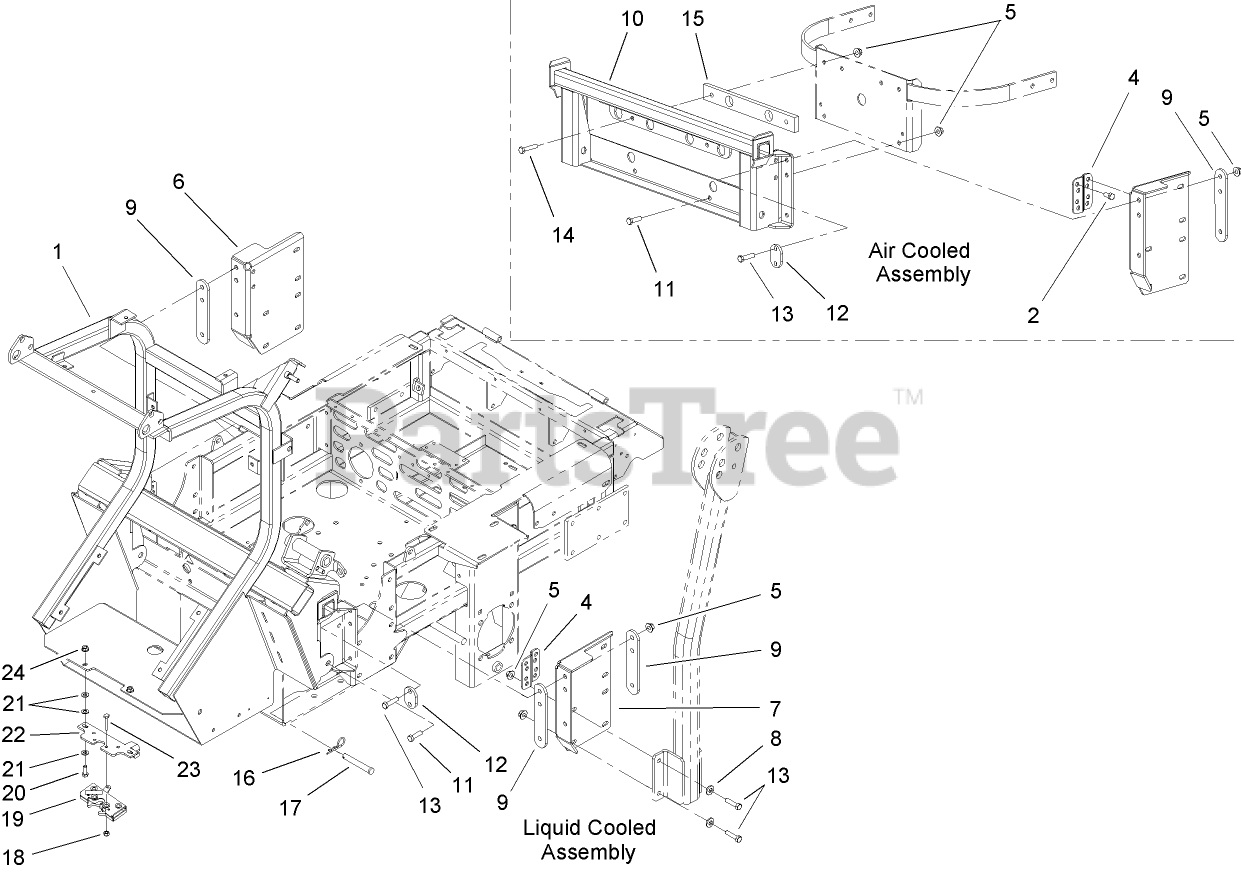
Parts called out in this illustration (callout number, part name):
1	HOPPER FRAME ASM
2	SCREW-HH
4	BRACKET-STIFFENER
5	NUT-HF
6	SUPPORT-BAGGER, LH
7	SUPPORT-BAGGER, RH
8	WASHER-BELLEVILLE
9	SPACER-FRAME
10	BAGGER MOUNT ASM
11	SCREW-HH
12	SPACER-FRAME, SHORT
13	SCREW-HH
14	SCREW-HH
15	SPACER-FRAME, BAGGER
16	PIN-COTTER
17	PIN-CLEVIS
18	NUT-LOCK, NI
19	LATCH-ROTOR
20	SCREW-HH
21	WASHER-PLAIN
22	BRACKET-LATCH
23	SCREW-HH
24	NUT-HF
